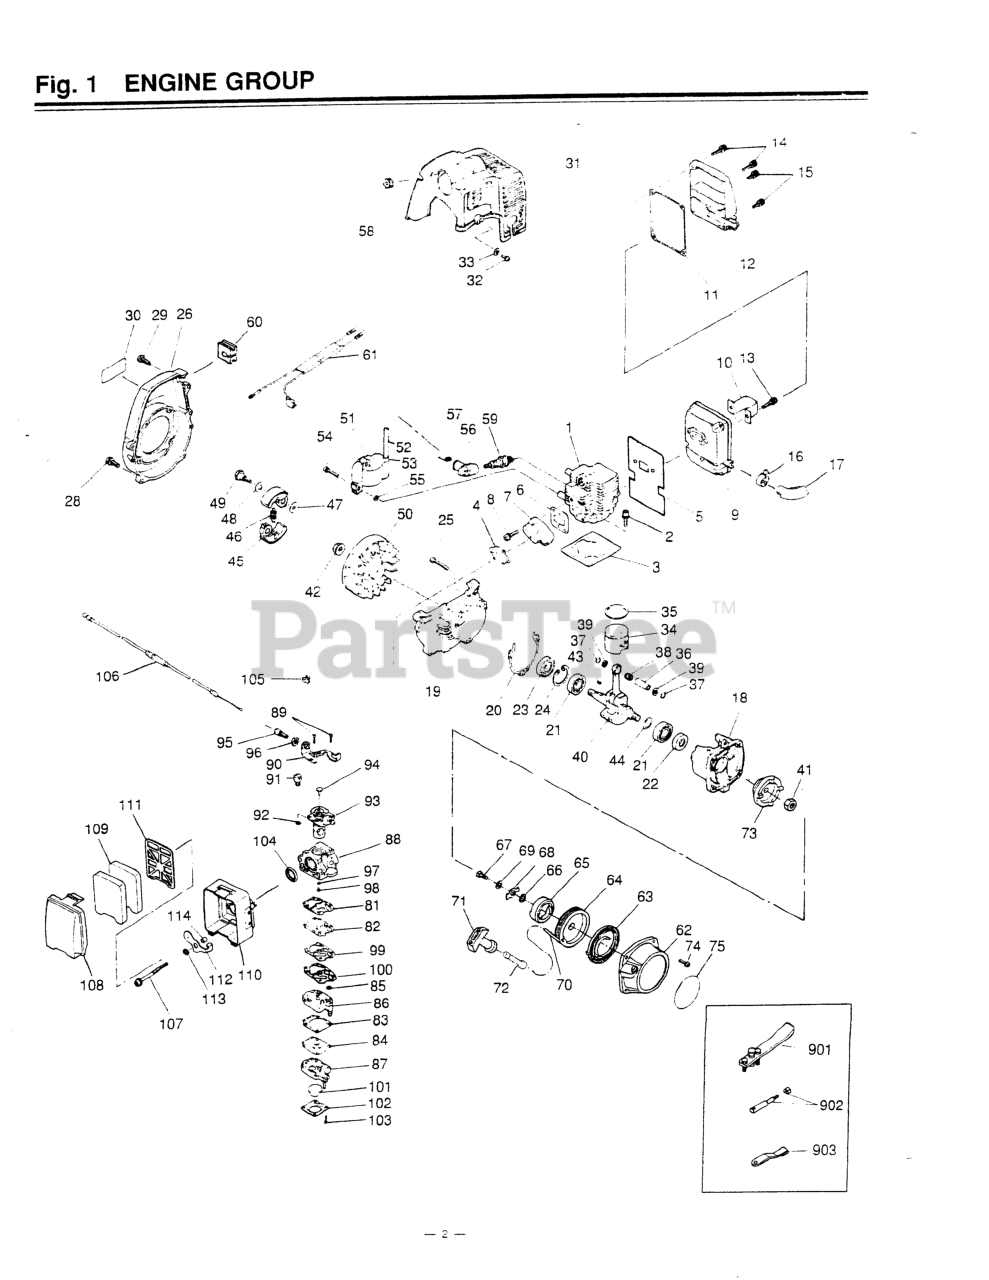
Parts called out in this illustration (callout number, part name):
1	CYLINDER
2	BOLT, M5 X 22
8	SCREW, M5 X 20
9	BODY, MUFFLER
13	BOLT, M6 X 18
14	BOLT, M5 X 22
15	BOLT (USE 3310-31720)
18	CRANKCASE (RPLS -21100)
19	CRANKCASE (RPLS -21100)
21	BEARING
23	SEAL, OIL (RPLS 1140-21220)
24	RING, SNAP, M28 x 1.2
25	SCREW, M5 x 30(RPLS 0263-00530
28	SCREW, M5 X 20
29	SCREW, HOUSING
32	SCREW, M4 x 12
33	WASHER
34	PISTON
35	RING, PISTON (RPLS 1850-41210)
36	PIN, PISTON 5x8x26
37	RING, SNAP (RPLS 1101-41320)
39	WASHER
43	KEY
44	SHIM (NO LONGER AVAILABLE)
47	WASHER, FLAT (USE 182303)
49	BOLT
51	COIL
52	CORD
53	CAP
54	SCREW, M4 X 22
57	SPRING
58	GROMMET
62	RECOIL ASSEMBLY (NLA)
63	SPRING, SPIRAL
66	WASHER
69	WASHER
74	SCREW, M4 X 16
75	LABEL
81	GASKET, PUMP
82	DIAPHRAGM
83	KIT ONLY
84	DIAPHRAGM (USE 4810-81260)
86	KIT ONLY
87	BODY
89	SCREW
91	SWIVEL
92	RING
93	VALVE ASSEMBLY
95	SCREW, CABLE ADJUSTER
96	NUT, CABLE ADJUSTER
97	RING, O
98	JET (NO LONGER AVAILABLE)
99	PLATE, PUMP (NLA)
100	GASKET, PLATE
101	PUMP, PRIMING
102	COVER
103	SCREW
104	RING, PACKING
105	CAP, CABLE END
106	CABLE (NLA)
108	COVER
109	FILTER
110	HOUSING
111	PLATE
113	WASHER
114	SLEEVE (REPLACES 1750-82060)
902	(H) ROD ASSY
